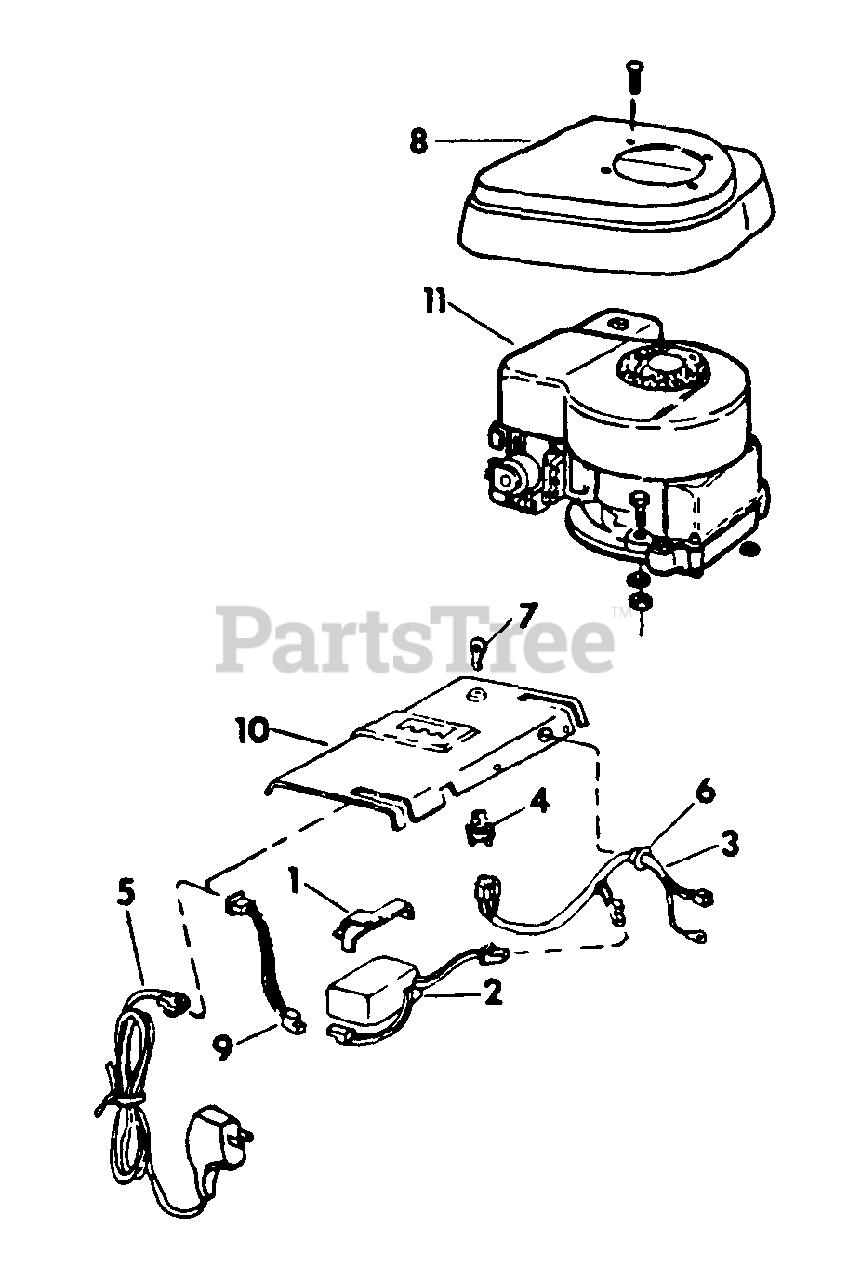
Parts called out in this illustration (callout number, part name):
1	RETAINER, BATTERY
2	BATTERY, 14.4 VOLTS (G.E.)
3	HARNESS, WIRE
4	SWITCH, ELECTRIC START
5	CHARGER, 12 VOLT
6	BUSHING, LOOM WIRE HARNESS
7	KEY, IGNITION
9	WIRE, EXTENSION
10	COVER, REAR DECK
11	ENGINE ASSY, 3.5 HP
